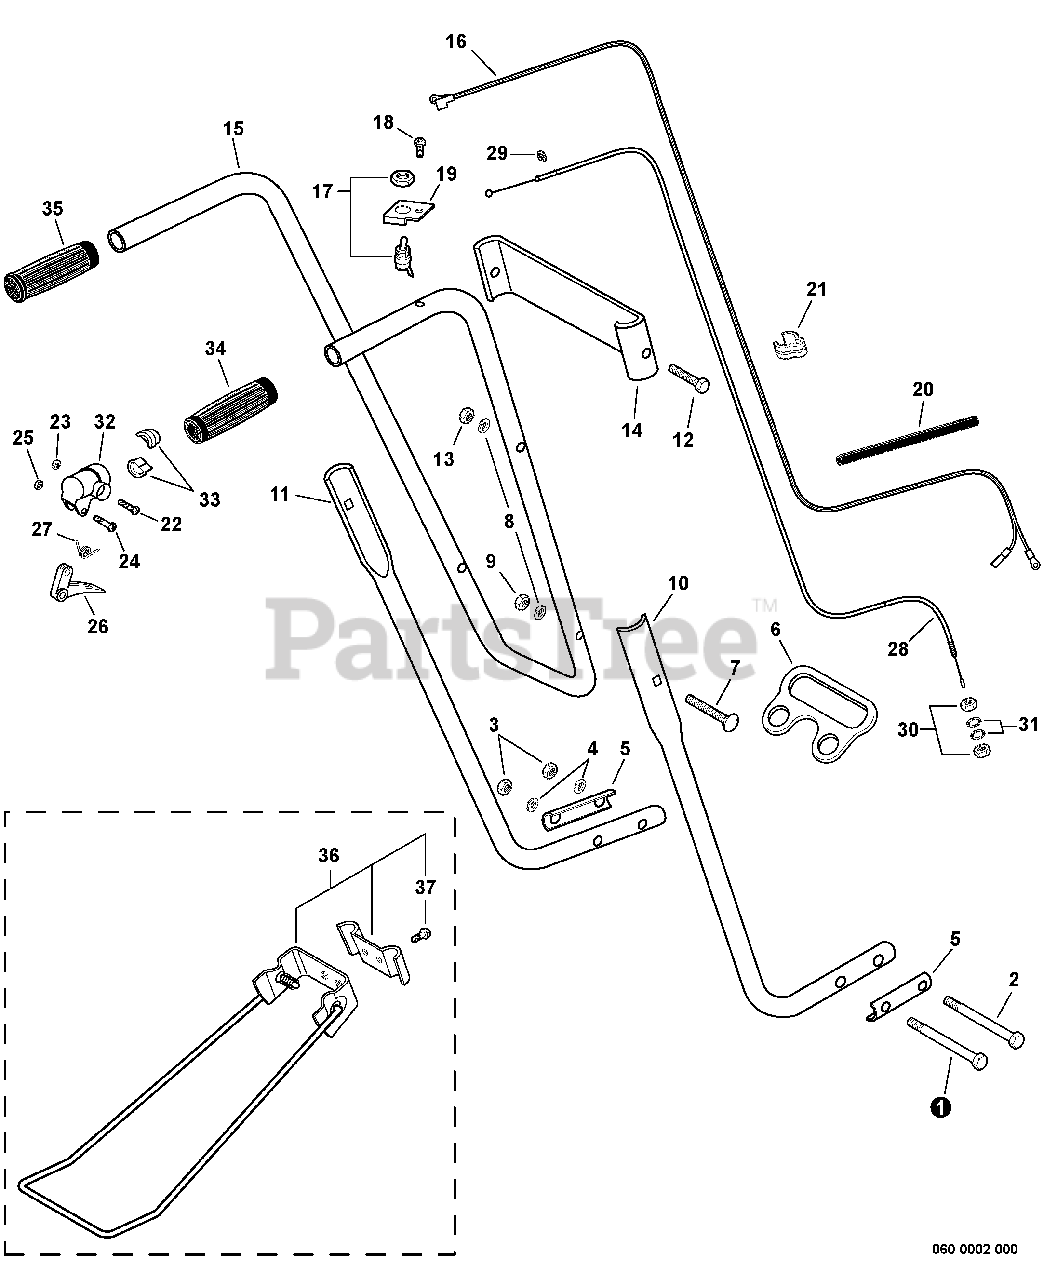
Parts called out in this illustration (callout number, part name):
1	BOLT 1/4"×3-1/4"
2	BOLT 1/4"×3"
3	NUT, LOCK 1/4
4	WASHER, SPRING
6	HANDLE, FRONT
8	WASHER, SPRING
10	HANDLE, LOWER
11	HANDLE, LOWER
12	BOLT 1/4"×1-1/4"
13	NUT, LOCK 1/4
14	BRACKET, HANDLE
15	HANDLE, UPPER
16	LEAD - GROUND
17	SWITCH, ON-OFF
18	SCREW 5×10
19	BRACKET, SWITCH
23	NUT, LOCK M5
25	NUT M5
26	TRIGGER, THROTTLE
28	CABLE, THROTTLE
31	WASHER, LOCK 6 MM
32	BRACKET, TRIGGER
34	GRIP, HANDLE
35	GRIP, HANDLE
36	KICK STAND KIT
37	BOLT 6×12
